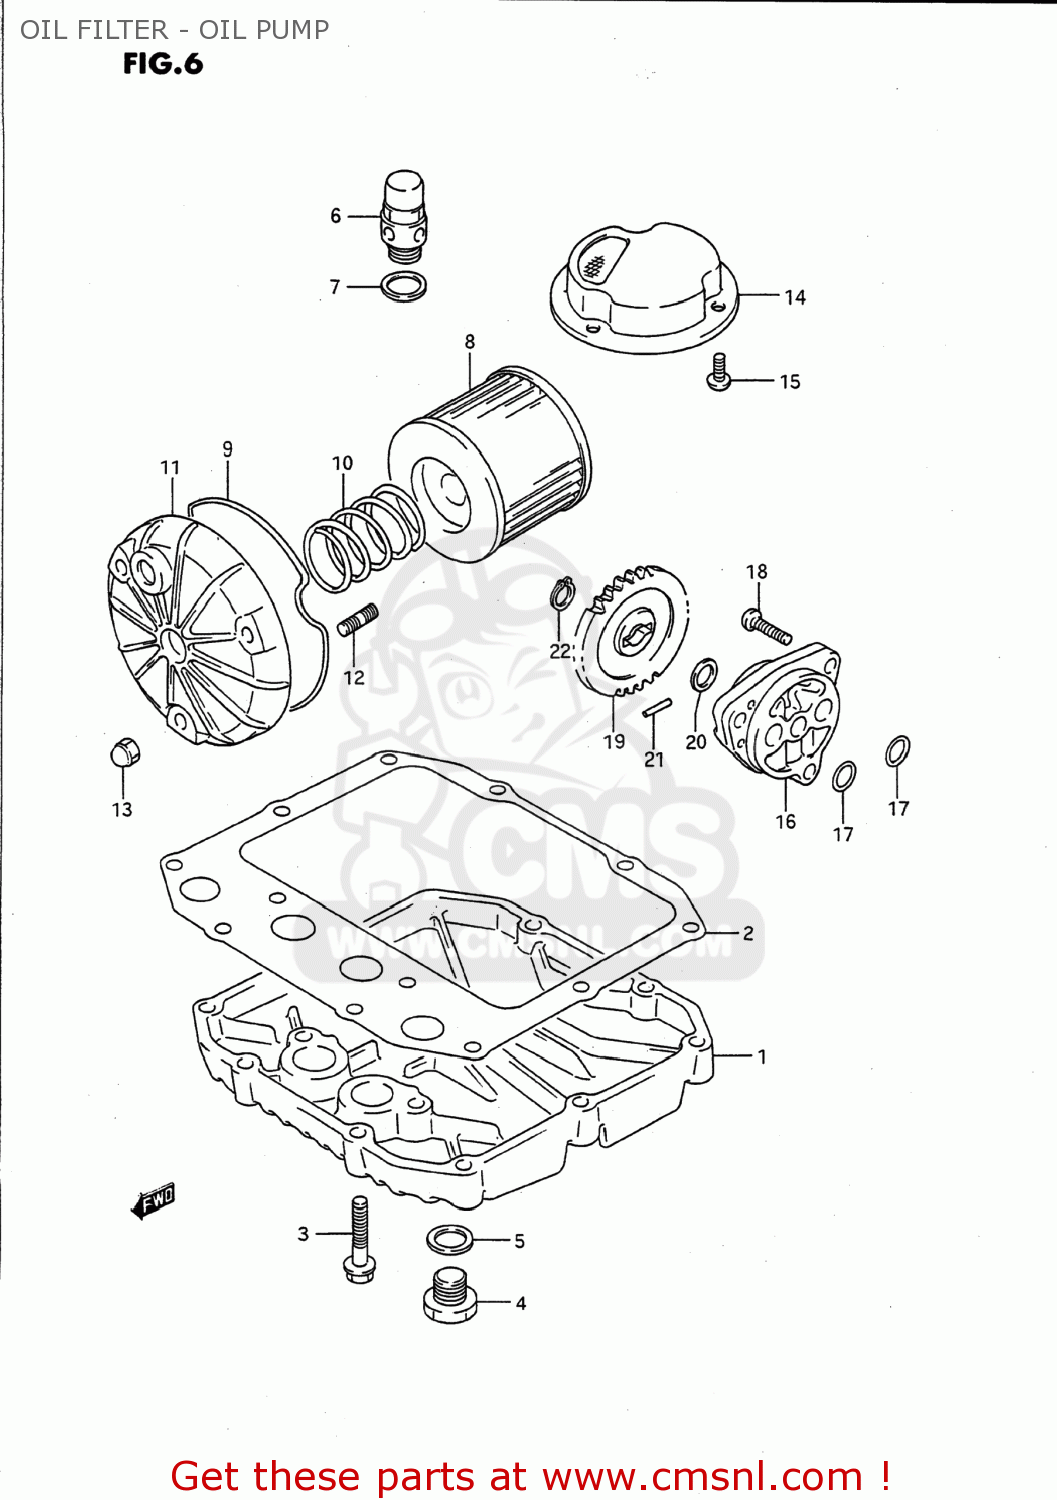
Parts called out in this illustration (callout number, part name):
1	PAN,OIL
2	GASKET,OIL PAN (NAS)
3	BOLT
4	PLUG
5	GASKET(13.8X18.8X4.8) (NAS)
6	VALVE ASSEMBLY,OIL RELIEF
7	WASHER
8	FILTER ASSY,ENGINE OIL
9	O RING,OIL FILTER CHAMBER CAP
10	SPRING
11	CAP,OIL FILTER
12	STUD 6X20
13	NUT
14	STRAINER,ENGINE OIL
15	SCREW
16	PUMP ASSY,ENGINE OIL
17	O RING(D:1.9,ID:13)
18	SCREW
19	GEAR,OIL PUMP DRIVEN
20	SHIM
21	PIN(4X15.8)
22	CIRCLIP,10MM
